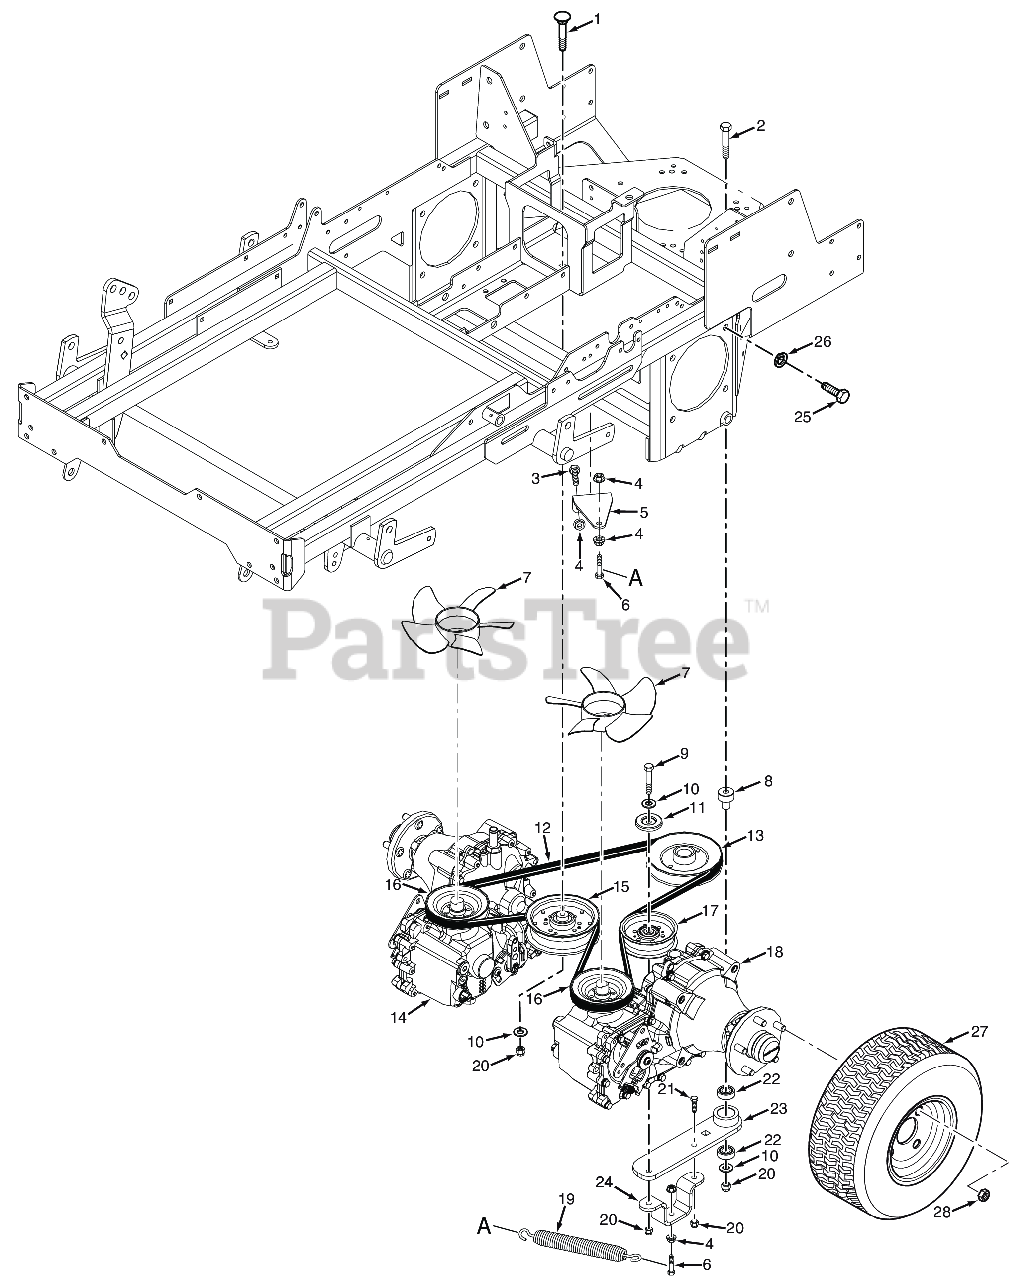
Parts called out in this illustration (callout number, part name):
1	Carriage Bolt, 3/8-16 x 2-1/2"
2	Bolt, Hex Head 3/8-16 x 3" - 52"
3	Bolt, Hex Head, 3/8-16 x 1 Gr. 5
4	NUT, 3/8-16 SERRATED FLANGE HEX HEAD
5	Mounting Bracket, Spring - Idler Arm
6	Bolt, Hex Head 3/8-16 x 1-1/2" Grade 8 Black
7	Kit, Fan / Pulley
8	Pivot, Idler Long - 52"
9	Capscrew, Hex Head 3/8-16 x 2.75"
10	Flatwasher, 3/8 (.391 x .938 x .105 HD) Grade 8
11	Quick Pin, 5/16" Dia.
12	Belt, Pump Drive STT
13	Pulley, 5.80" Dia. - 1.125 Bore
14	Transaxle, RH
15	Idler Pulley, Belt Clutch
16	Kit, Fan / Pulley
17	Pulley, 4" Dia. Idler
18	Transaxle, LH
19	Spring, Pump Drive
20	HEX NUT, ELASTIC STOP LOCK, 3/8-16
21	Bolt, Hex Head 3/8-16 x 1-1/4", Kawasaki FX / FS
22	BEARINGS, BALL, NEUTRAL RETURN
23	Idler Arm Assembly
24	Mounting Bracket, Idler
25	Bolt, Hex Head 1/2-13 x 1-1/4"
26	Lockwasher, 1/2" Spring
27	Wheel Assembly, 24 x 12-12 4-Ply (5-Hole)
27	Rim w/Valve Stem
27	Tire, 24 x 12-12 Turf Master
28	Wheel Nut, 1/2-20 x 13/16
